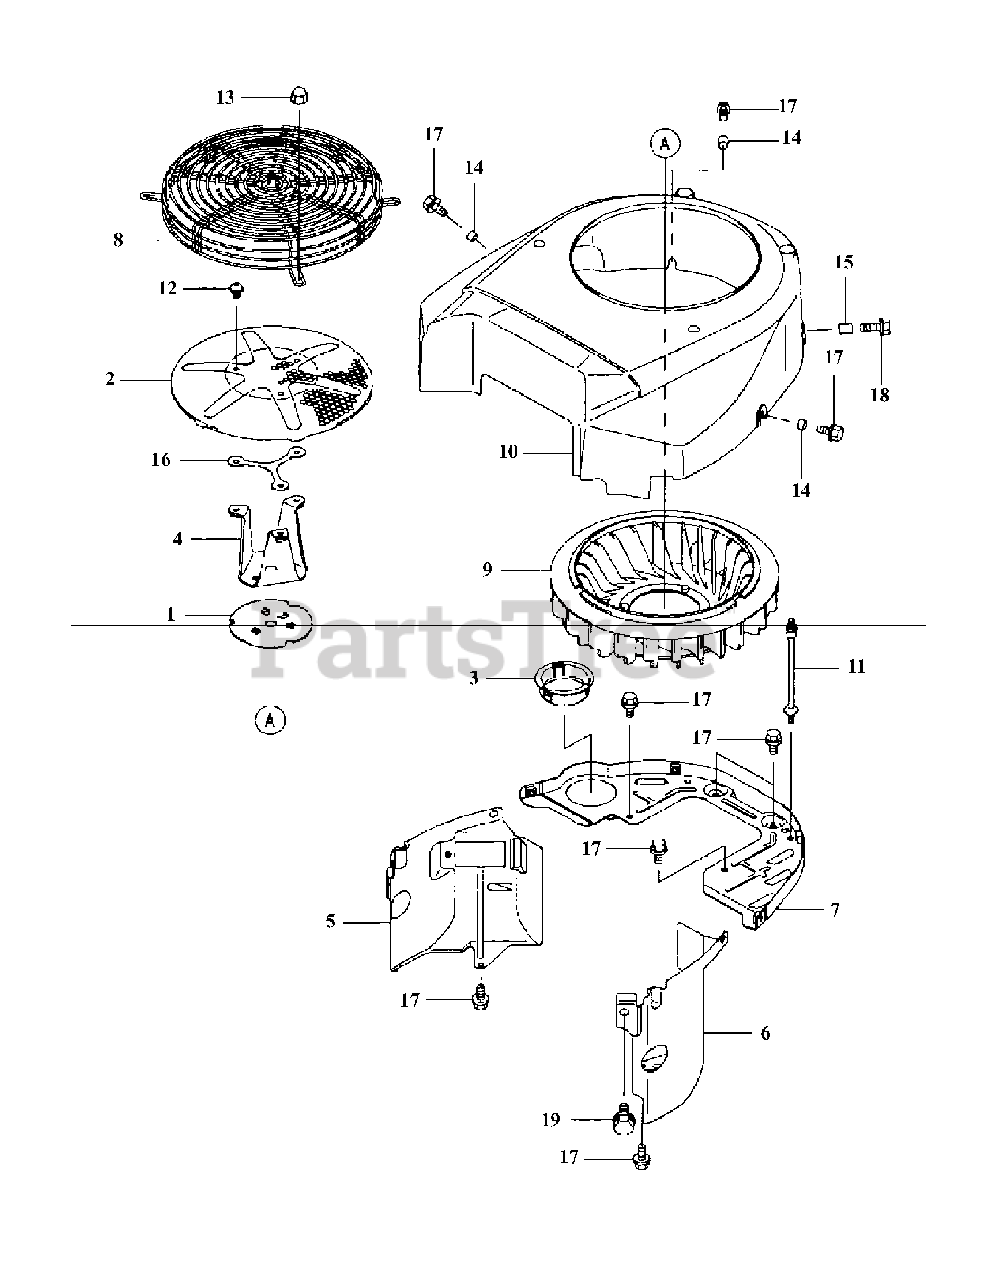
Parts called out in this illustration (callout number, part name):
4	Bracket
5	Shroud-Engine
6	Shroud-Engine
7	Shroud-Engine
14	Spacer, 6.2x7.9x5
15	Spacer, 6.5x7.9x10.5
